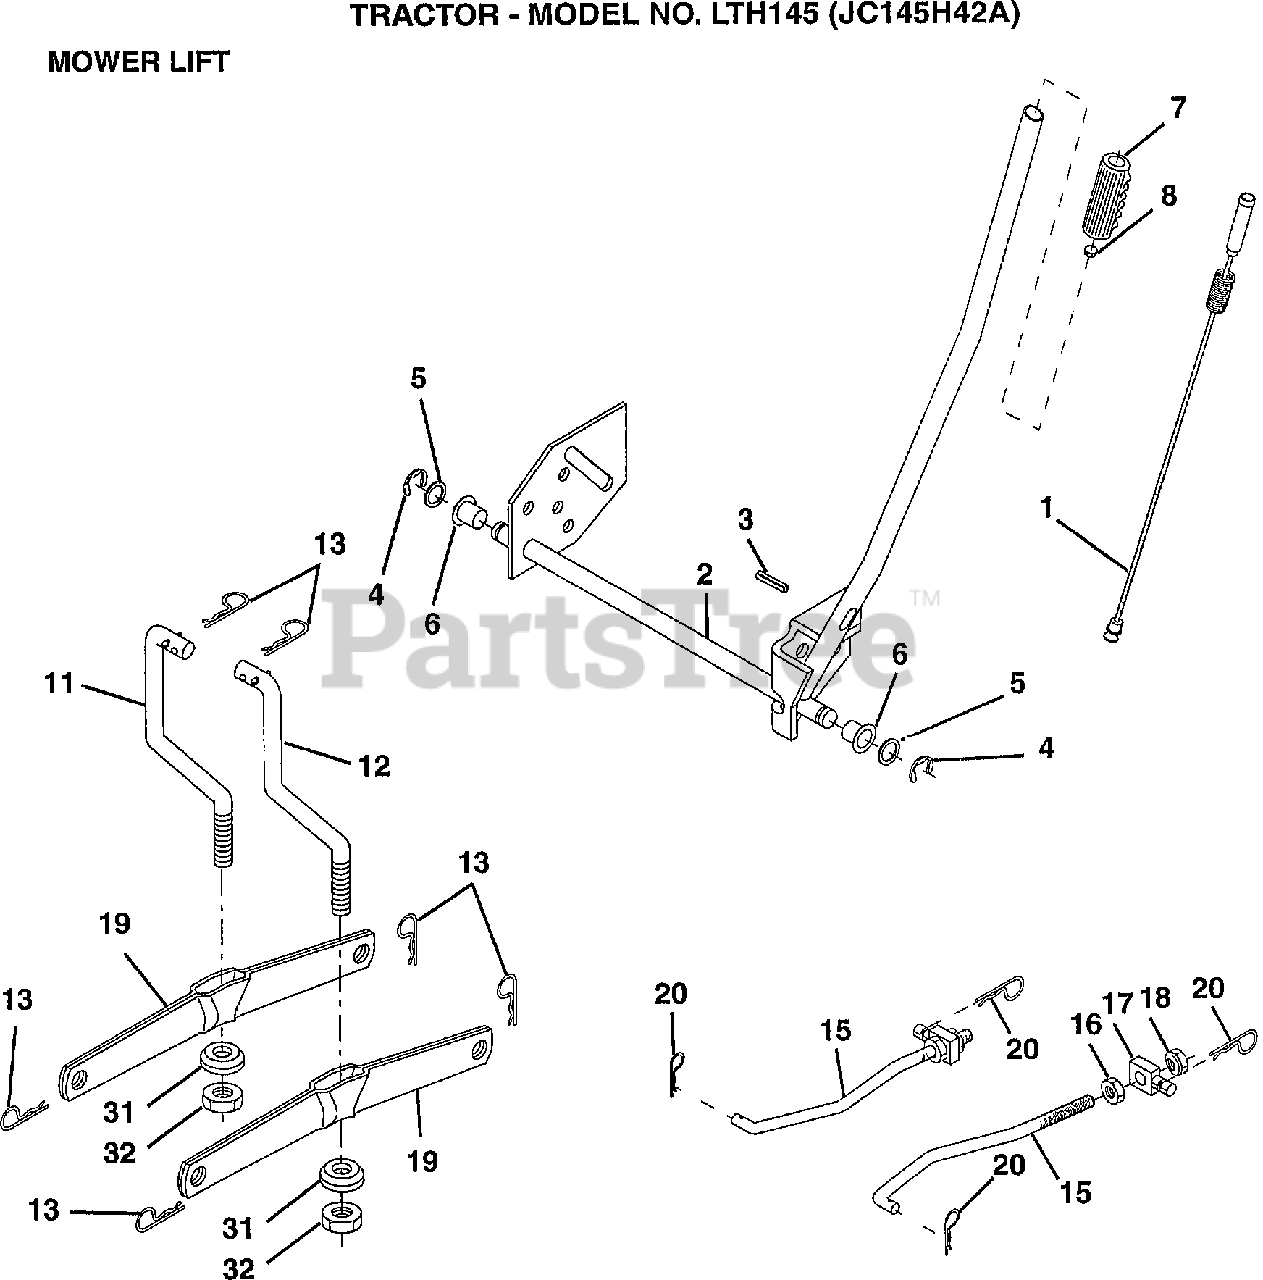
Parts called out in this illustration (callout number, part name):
4	E RING #5133-62
5	WASHER PLTD 21/32 X 1 X 21 GA
16	NUT JAM HEX 1/2-13
18	NUT LOCK W/WSH 1/2-13
32	NUT CROWNLOCK 3/8-24
